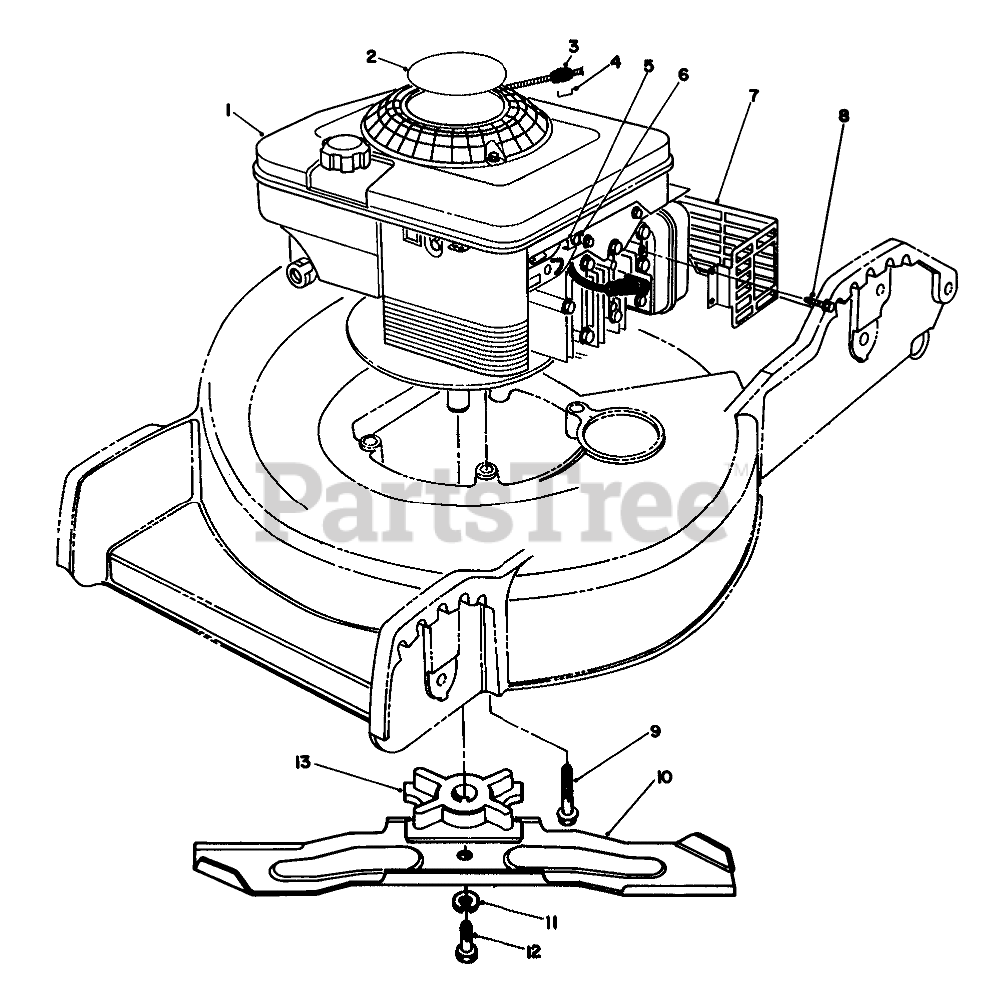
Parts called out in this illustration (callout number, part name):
2	DECAL - ENGINE
3	Stop-Rope
4	Staple
5	CLAMP-CASING
6	Screw
7	SHIELD-MUFFLER
8	SCREW-HWH
9	3/8-16X2 TAPTITE HEX HD
10	Blade
11	WASHER-LOCK
12	SCREW-HH
13	BLADE RETAINER
